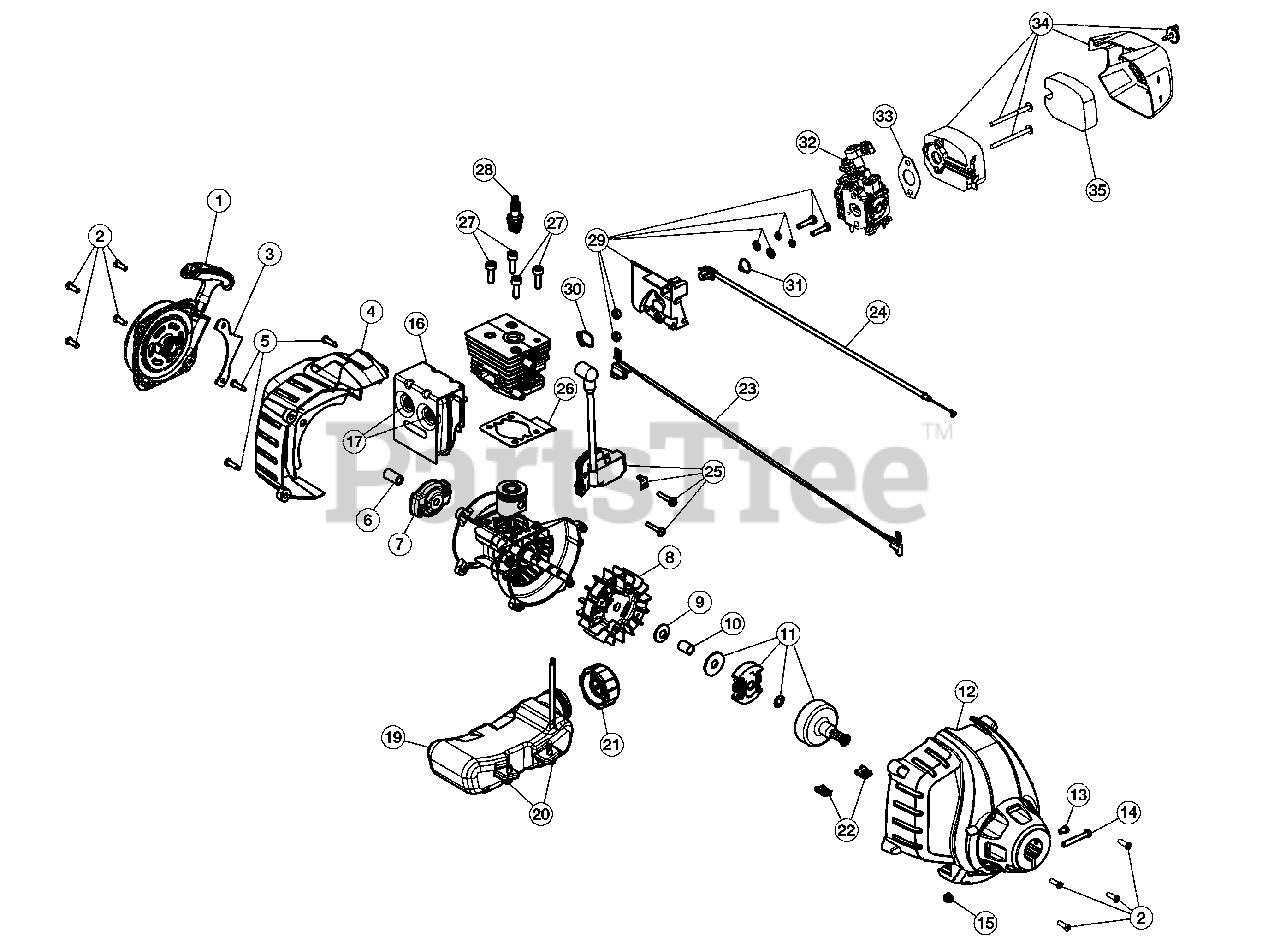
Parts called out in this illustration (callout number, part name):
1	Starter Assembly (Incl. 2 & 3)
2	Starter Screw
3	Starter Assembly Guard (Incl. 2)
4	Rear Engine Cover (Incl. 5)
5	Cover Screw
7	Pawl Assembly
8	Flywheel Assembly
11	Clutch Assembly
12	Clutch Cover Assembly (Incl. 2, 13 -15 and 22)
13	Anti-rotation Screw
14	Clamp Screw
15	Clamp Nut
16	Muffler Assembly (Includes 17)
17	Muffler Screw
19	Fuel Tank Assembly (Incl. 20 and 21)
22	U-shaped Nut
23	Lead Wires
24	Throttle Cable
25	Module Assembly
26	Cylinder Gasket
27	Cylinder Bolt
28	Spark Plug
29	Insulator Assembly (Incl. 30 and 31)
30	Insulator O-Ring
31	Carburetor O-Ring
32	Carburetor
33	Carburetor Gasket
34	Air Cleaner Assembly (Incl. 35)
35	Air Cleaner Filter
